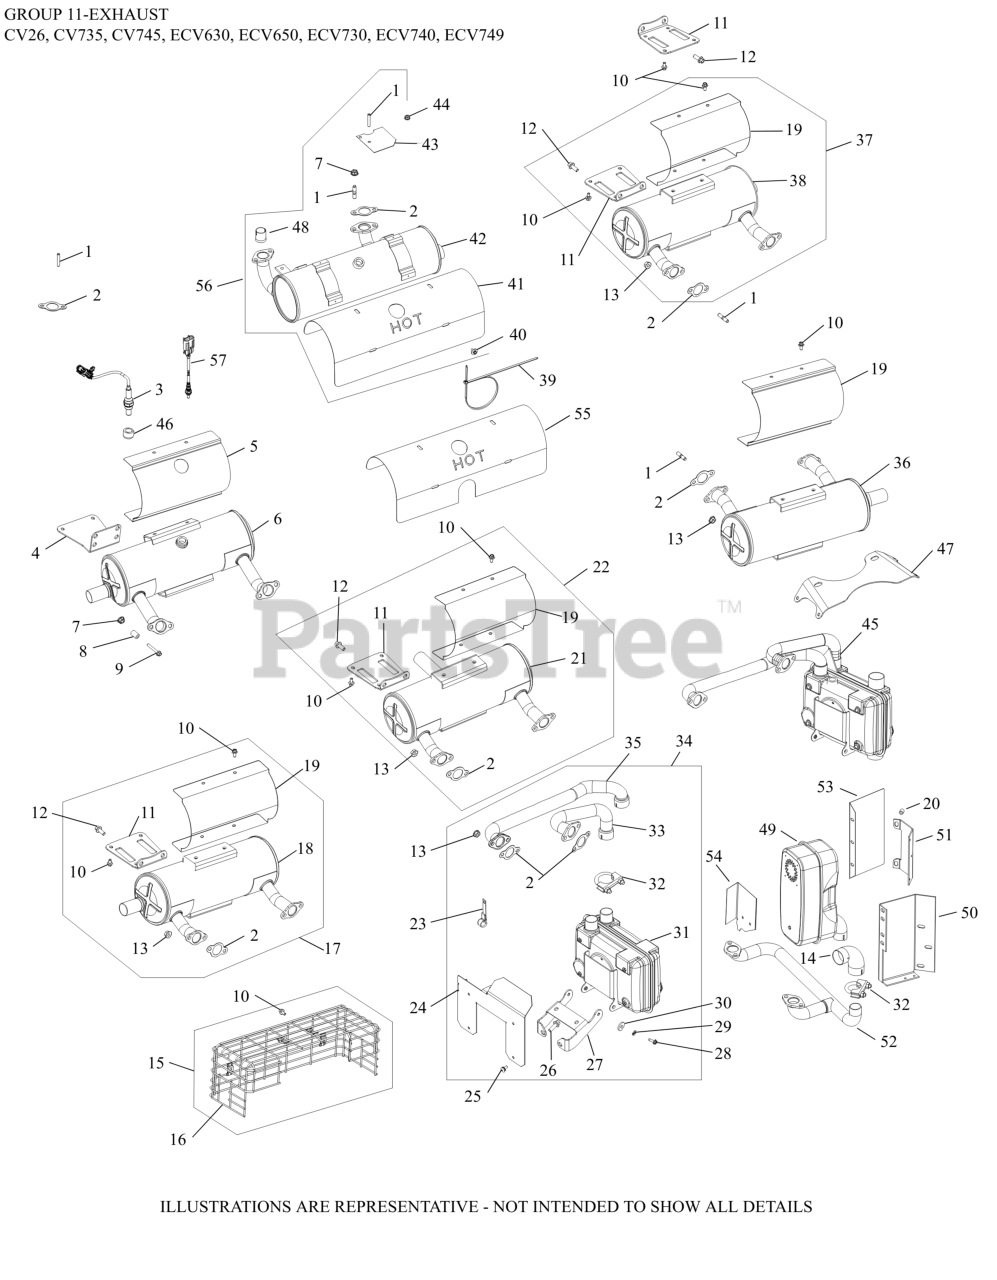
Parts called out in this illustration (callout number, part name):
2	GASKET, EXHAUST
3	SENSOR, OXYGEN (M18 x 1.5 THREADS)
7	NUT, HEX FLANGE LOCK (M8)
